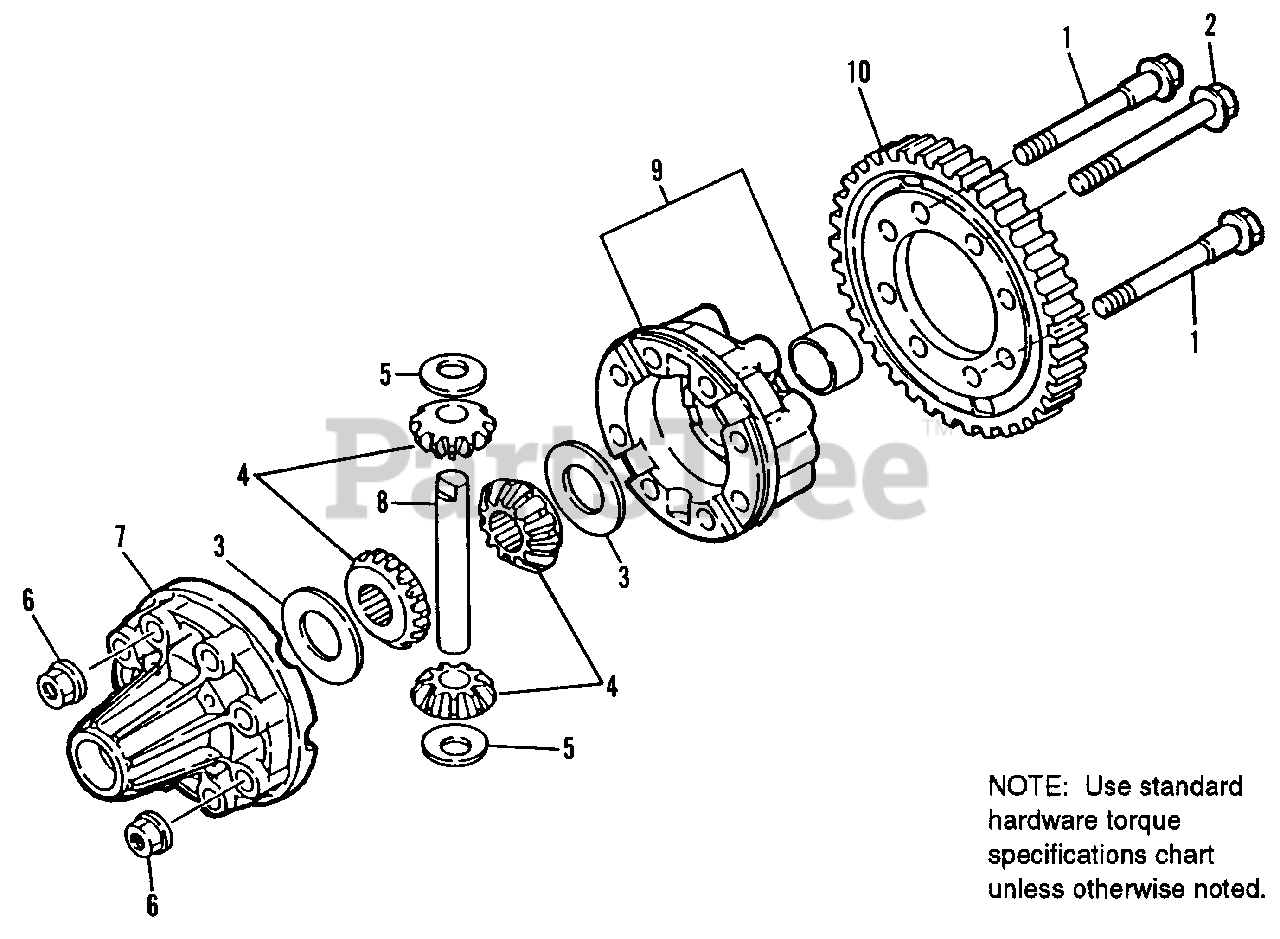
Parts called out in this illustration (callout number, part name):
4	GEAR SET, Differential
5	WASHER, Diff. Pinion
7	CASE, B, Differential
8	SHAFT, Diff. Pinion
9	CASE, A, Diff. Assy.
10	GEAR, 64 Tooth, Final
